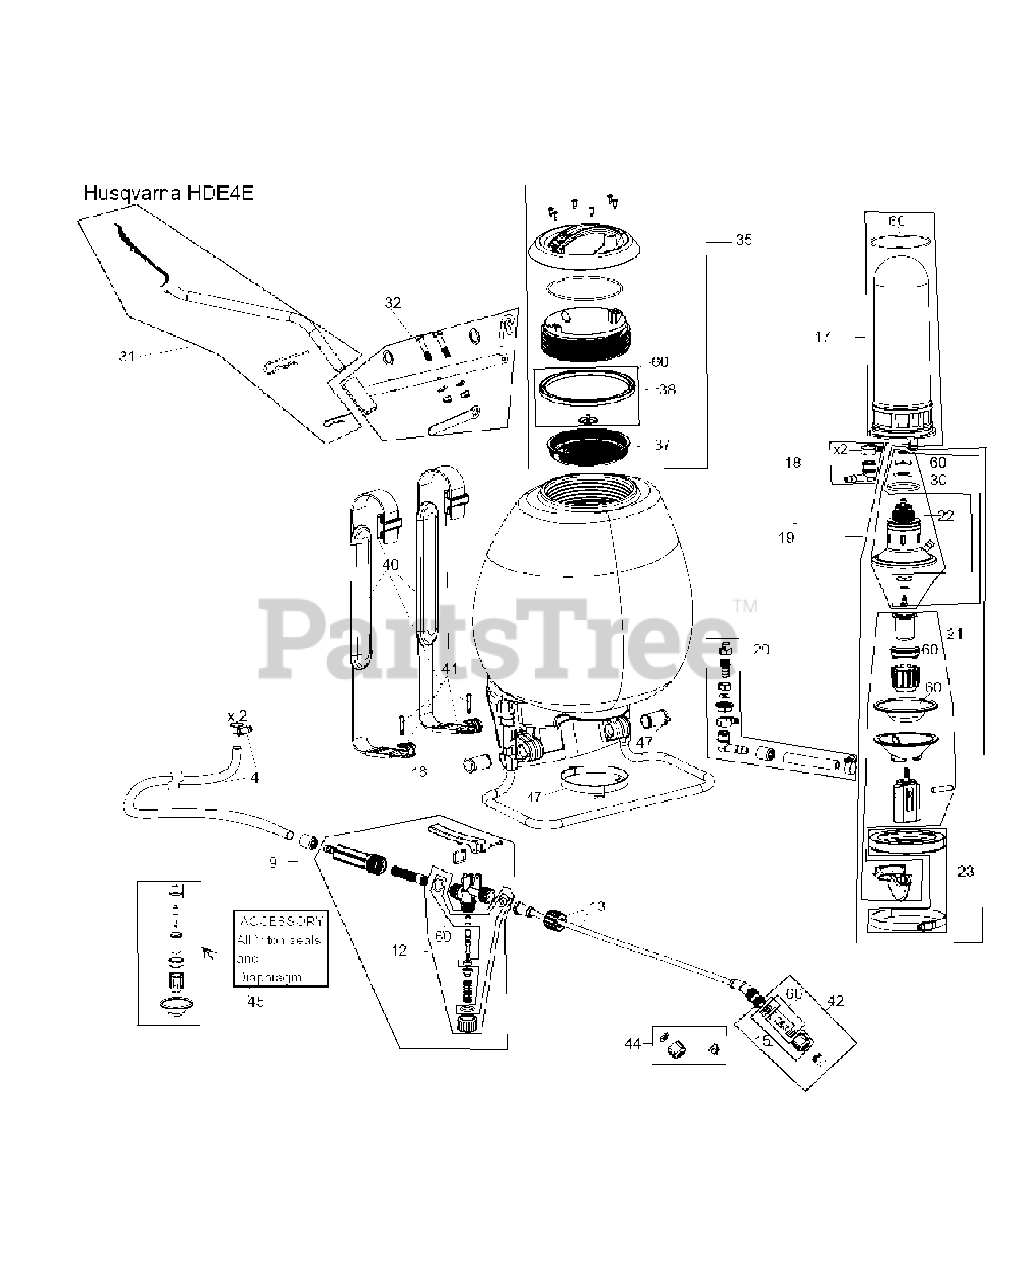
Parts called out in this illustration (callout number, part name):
4	HOSE AND 2 HOSE CLAMPS
9	COMP SPRAY PISTOL WBUILTNFILTE
12	SPINDLE SET
13	BRASS SPRAY WAND 20"
15	NOZZLE HOLDER
16	SILICONE GREASE
17	PRESSURE CHAMBER ORIN
18	Fitting and Clamp, 90 Degree
19	PUMP MODULE COMPLETE
20	HOSE CLAMPS TANK CONN
21	DIAPHRAGM PISTON PUMP
23	HANDLE HALF W/ CLAMP
30	DIAPHRAGM VITON SEALS
31	PUMP HANDLE (FOLD-BACK TYPE)
32	PUMP LEVER
35	BACKPACK LID SEAL
40	SHOULDER STRAPS (SET OF 2)
41	BUCKLE HOOK FOR STRAP
42	Adjustable Nozzle, Brass with Holder
44	PLASTIC SPRAY TIP SET (2-8004)
45	VITON DIAPHRAGM COMPL
46	Nylon Bearing
60	SEAL SET COMPLETE HDE
